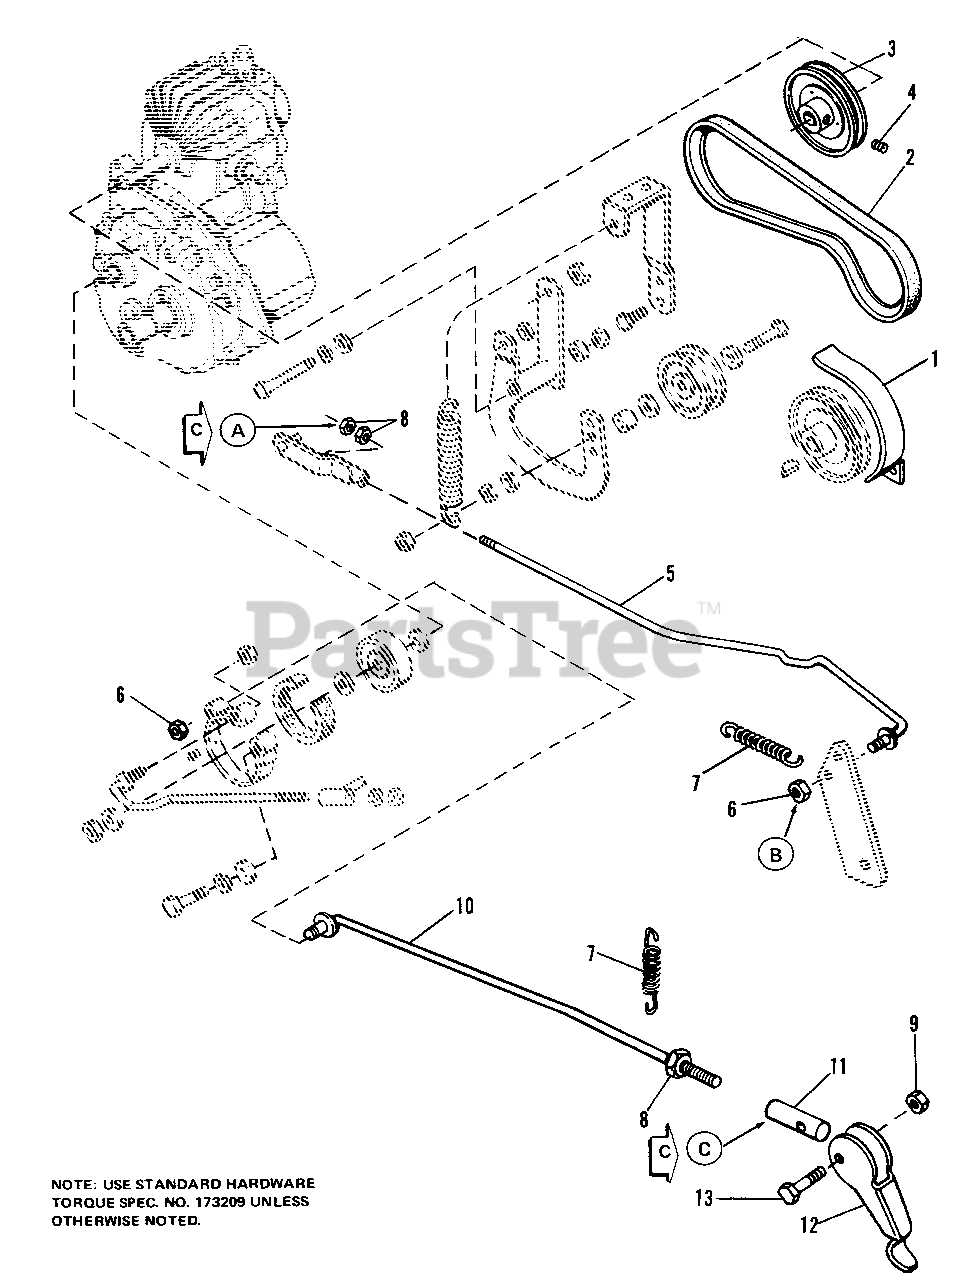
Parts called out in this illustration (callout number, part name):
2	"V" BELT, Hydro Pump
3	PULLEY
4	SETSCREW, Sq. Hd., 5/16-18 x 3/8
5	ROD, Clutch
6	NUT, Lock, Hex, 5/16-18
8	NUT, Hex, Full, 5/16-18
9	NUT, Lock, Hex, 1/4-20
12	LEVER, Parking Brake
13	CAPSCREW, Hex Hd., 1/4-20 x 1-1/4
